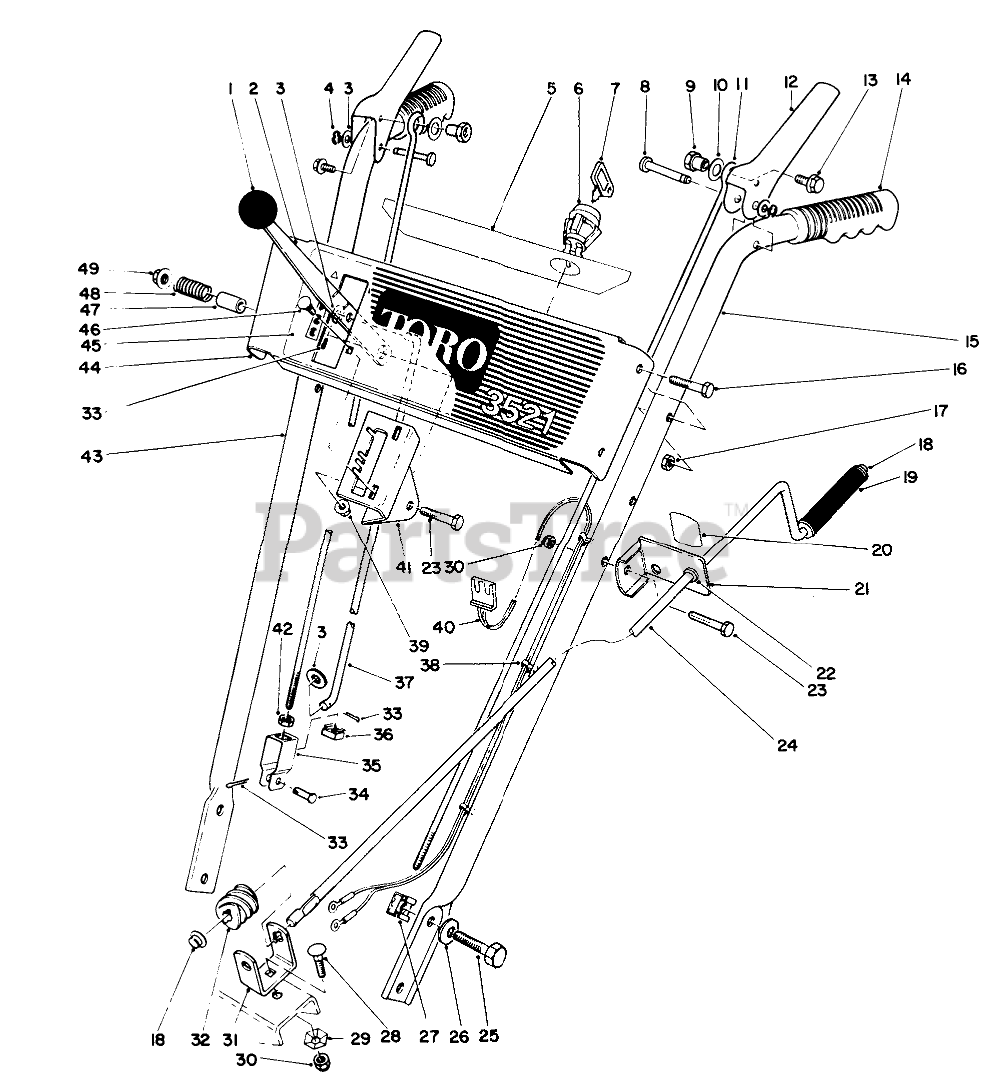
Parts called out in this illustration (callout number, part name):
2	SPEED SELECTOR B
3	WASHER-PLAIN
4	RING-CLIP
5	Decal-Escutcheon Back
6	SWITCH
7	KEY-IGNITION
8	PIN-LEVER, CONTROL
9	POST-MOUNTING, LINKAGE
10	WASHER-FLAT
11	LINK-UPPER
12	HANDLE-CONTROL
13	SCREW-HHF
14	Grip
15	LEFT HANDLE
16	SCREW-HH
17	Nut-Lock
18	RETAINER-PUSH ON
19	Grip-Rod
20	DECAL-CHUTE DIRECTION
21	Bracket-Chute Control (Incl. Ref. #20 & 22)
22	Bushing
23	SCREW-HH
24	ROD-CONTROL, CHUTE
25	SCREW-HH
26	WASHER-BELLEVILLE
28	BOLT-CARR
29	WASHER-LOCK
30	NUT-LOCK, NI
31	BRACKET-WORM
32	GEAR-WORM, CHUTE
33	PIN-COTTER
34	PIN-CLEVIS
35	CLEVIS
36	NUT-RETAINED
37	ROD-SELECTOR, SPEED
38	Mount-Wire
39	NUT-HHF
40	Wire Harness Assembly (Incl. Ref. #38)
41	Mount-Speed Selector
42	NUT-JAM
43	RIGHT HANDLE
44	ESCUTCHEON PLT B
45	Decal-3521
46	SCREW-CARRIAGE
47	SPACER
48	SPRING
49	NUT-HF
